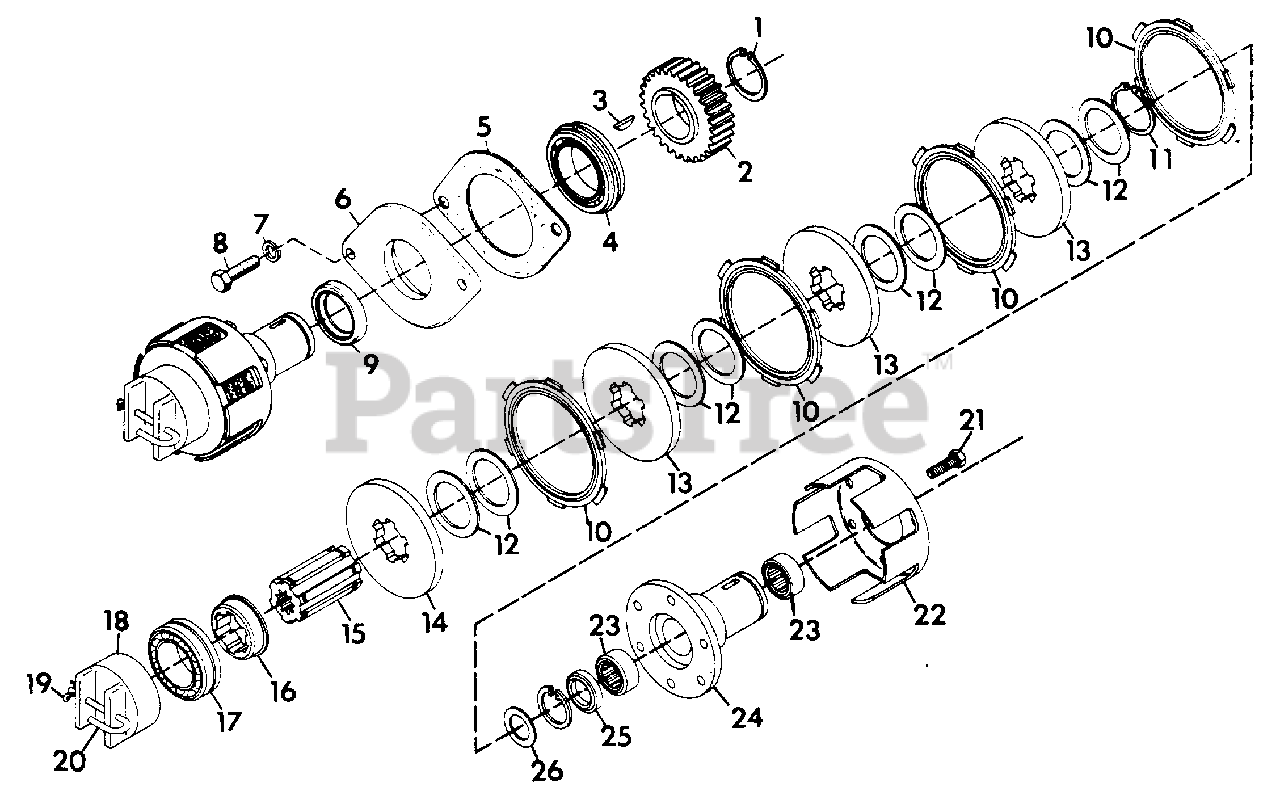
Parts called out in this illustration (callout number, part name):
1	RING, RETAINING 1.562 SHAFT
2	GEAR, PTO
3	KEY, WOODRUFF .187X.75 HARD #9
4	BEARING, BALL 1.574X3.149X.708
5	GASKET, FRONT PTO CAP
6	CAP, FRONT PTO
7	WASHER, LOCK 5/16 REG.
8	BOLT, HEX 5/16-18X.75
9	SEAL, CLUTCH OIL
10	DISC, FRICTION
11	RING, RETAINING
12	SPRING, SEPARATOR BELLEVILLE
13	DISC, CLUTCH
14	CLUTCH, PRESSURE PLATE
15	HUB, PTO CLUTCH DISC
16	ADAPTOR, PTO CLUTCH CAM
17	BEARING, BALL 1.574X3.149X.70
18	TRUNNION, FWD-REV CLUTCH
19	PIN, COTTER .06X.75
20	PIN, CLUTCH SPRING
21	BOLT, HEX 5/16-18X.50
22	CUP, DRIVEN
23	BEARING, NEEDLE .750X1.000X.500
24	HUB, PTO CLUTCH
25	SEAL, OIL .750X1.254X.188
26	RACE, BEARING THRUST .752X1.240X.03
